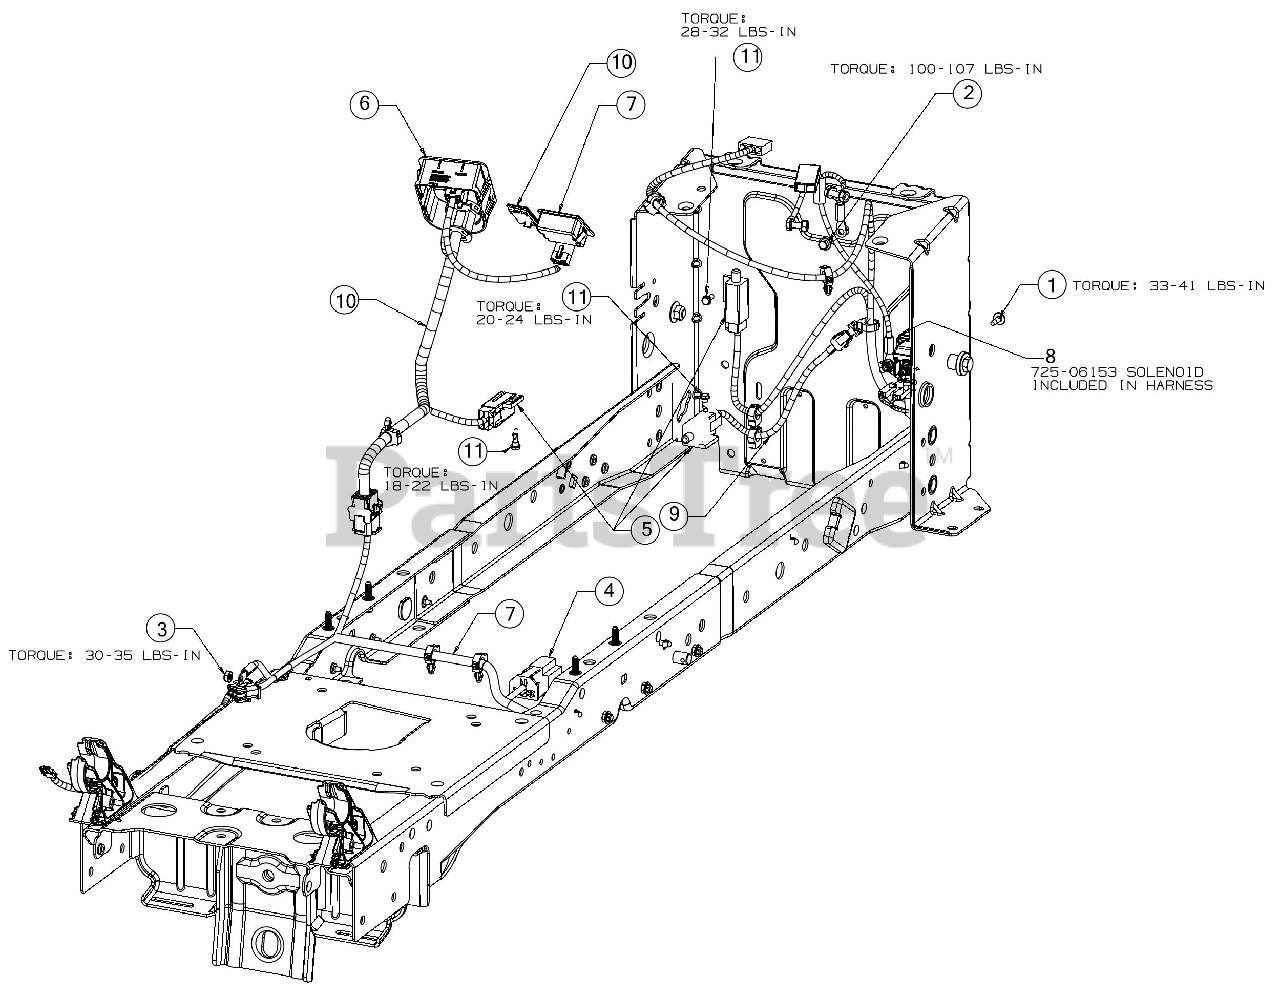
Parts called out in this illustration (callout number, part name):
1	SCREW M6-1 X .625
2	SCREW 1/4-20X.625
3	HEX NUT 1/4-20
4	3 POLE SWITCH ( NC-NO-NO)
5	INTERLOCK SWITCH (NO/NC)
6	KEY SWITCH MODULE
7	SERVICE MINDER
8	REVERSE HARNESS
11	SHOULDER SCREW
12	MAIN HARNESS M-PTO/RMC/HRMTR
